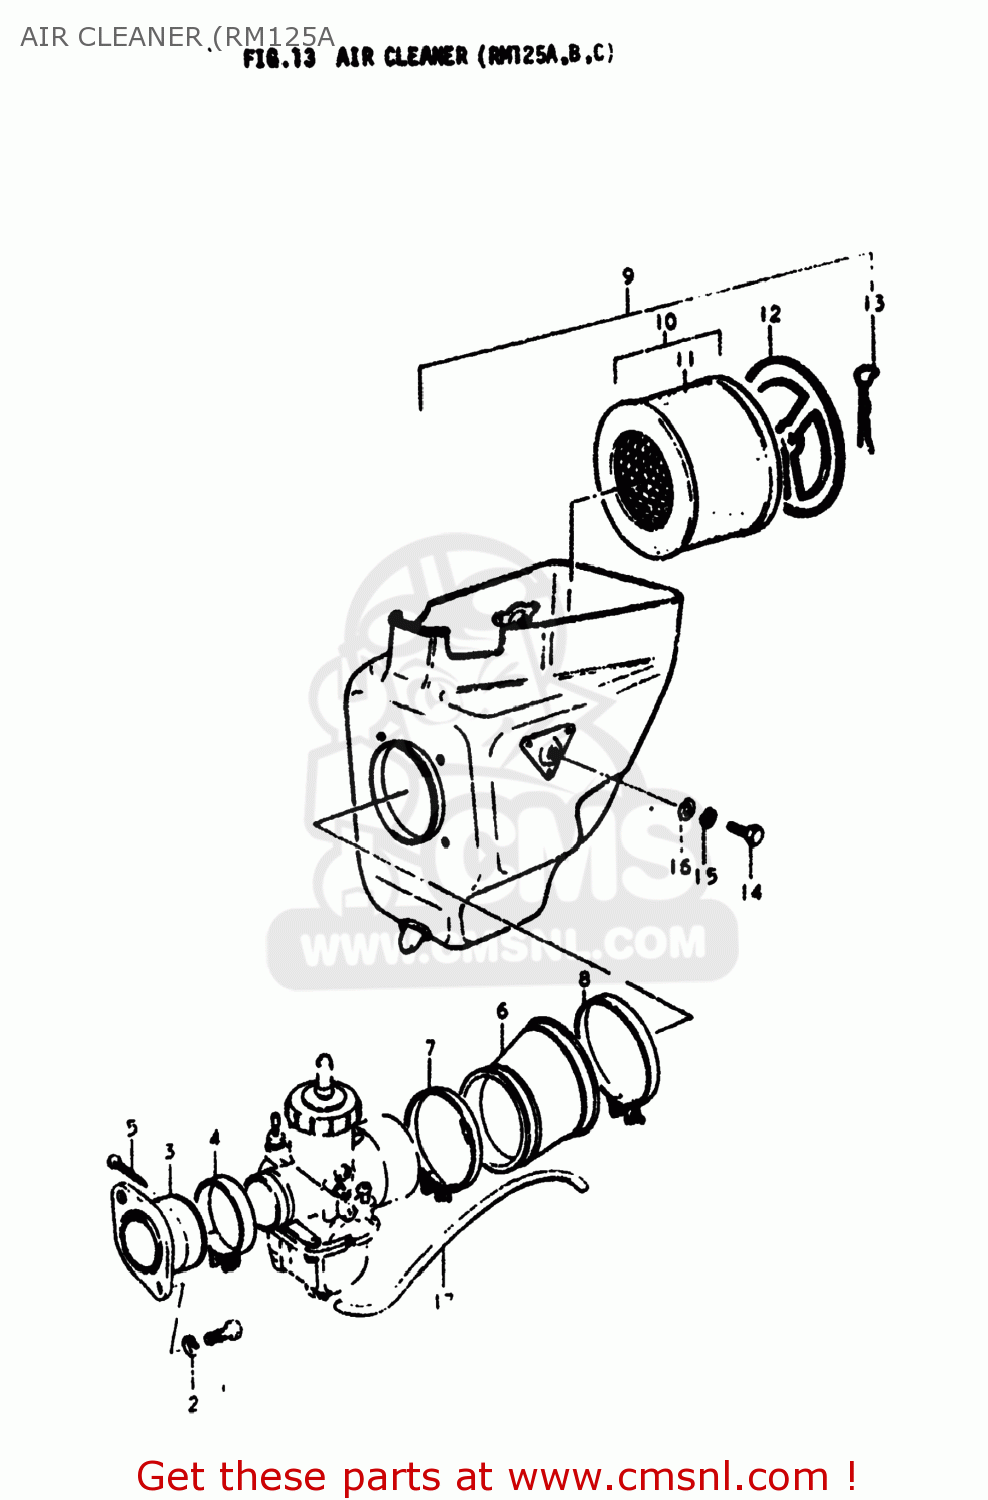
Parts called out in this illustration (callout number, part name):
1	BOLT
2	LOCK WASHER
3	PIPE,INTAKE
4	CLAMP
5	SCREW 5X20
6	HOSE,CARBURETOR AIR INLET
7	CLAMP
8	CLAMP
9	CLEANER ASSEMBLY,AIR
10	FILTER ASSY,AIR CLEANER
11	ELEMENT,AIR CLEANER
12	CAP
13	SPRING,AIR CLEANER
14	BOLT
15	LOCK WASHER
16	WASHER
17	HOSE
